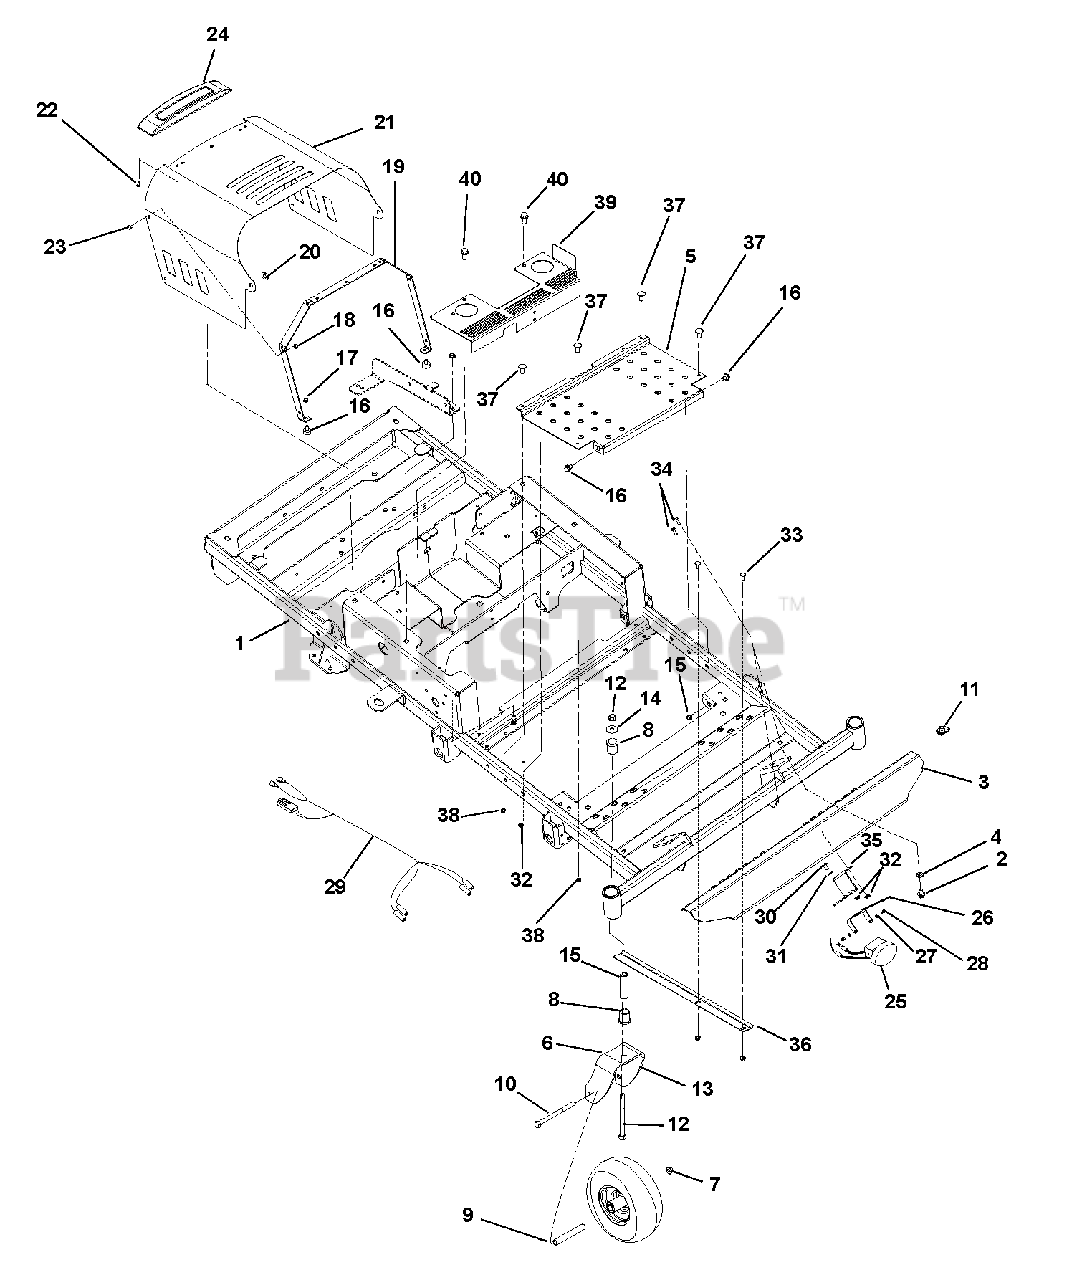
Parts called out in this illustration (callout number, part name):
1	Weldment, Frame XL
2	Bolt, Hex .38-16 x 1.00 Grade 5
3	Weldment, Footrest
4	Washer, Locking .38 x .094 Regular
5	Deck Access Panel
6	Fork, Caster
7	Wheel/Tire Assembly, 11.0 x 4.0 x 5.0, Monitor
8	Bushing, Flange 1.00 x 1.25 x 1.50 x 1.50
9	Spacer, Wheel
10	Bolt, Hex .50-13 x 6.50 Grade 5
11	Nut, Retainer .375-16 x .37
12	Nut, Locking Top Flange .50-13
13	Bolt, Hex .50-13 x 5.00 Grade 5
14	Washer, Flat Steel .511 x 1.441 x .125
15	Spacer, Caster Fork
16	Bumper, Rubber
17	Nut, Locking Top Flange .31-18
18	Nut, Locking Top Flange .25-20
19	Bracket, Hood Brace
20	Washer, Flat Nylon .52 x 1.00 x .08
21	Hood, ZT XL
22	Screw, .25 x .50 PN Head
23	Bolt, Round Head Square Neck .25-20 x .50 Grade 5
24	Trim, ZT XL Hood
25	Kit, Zoom/ZT XL Light
26	Bracket, Light
27	Washer, Locking 4MM x 1MM Regular Cone Lock
28	Screw, M4 x .07 x 8 Socket Head Cap
29	Harness, Mini-Z Headlight
30	Screw, Cap Button Head .31-18 x .50 Grade 5
31	Washer, Locking .31 x .078 Regular
32	Nut, .25-20 Nyloc Flange (Serial Number 6059 +)
33	Bolt, Round Head Square Neck .31-18 x .75 Grade 5
34	Bolt, Hex .25-20 x .75 Grade 5
35	Bracket, Light Mount
36	Bracket, Light Harness
37	Bolt, Hex .31-18 x 1.00 Grade 5
38	Nut, Locking-Nylon-Flange .31-18
39	Bracket, XL CE Fan Guard
40	Screw, Tapping .38-16 x .50 Hex Washer Head Thread Rolling
